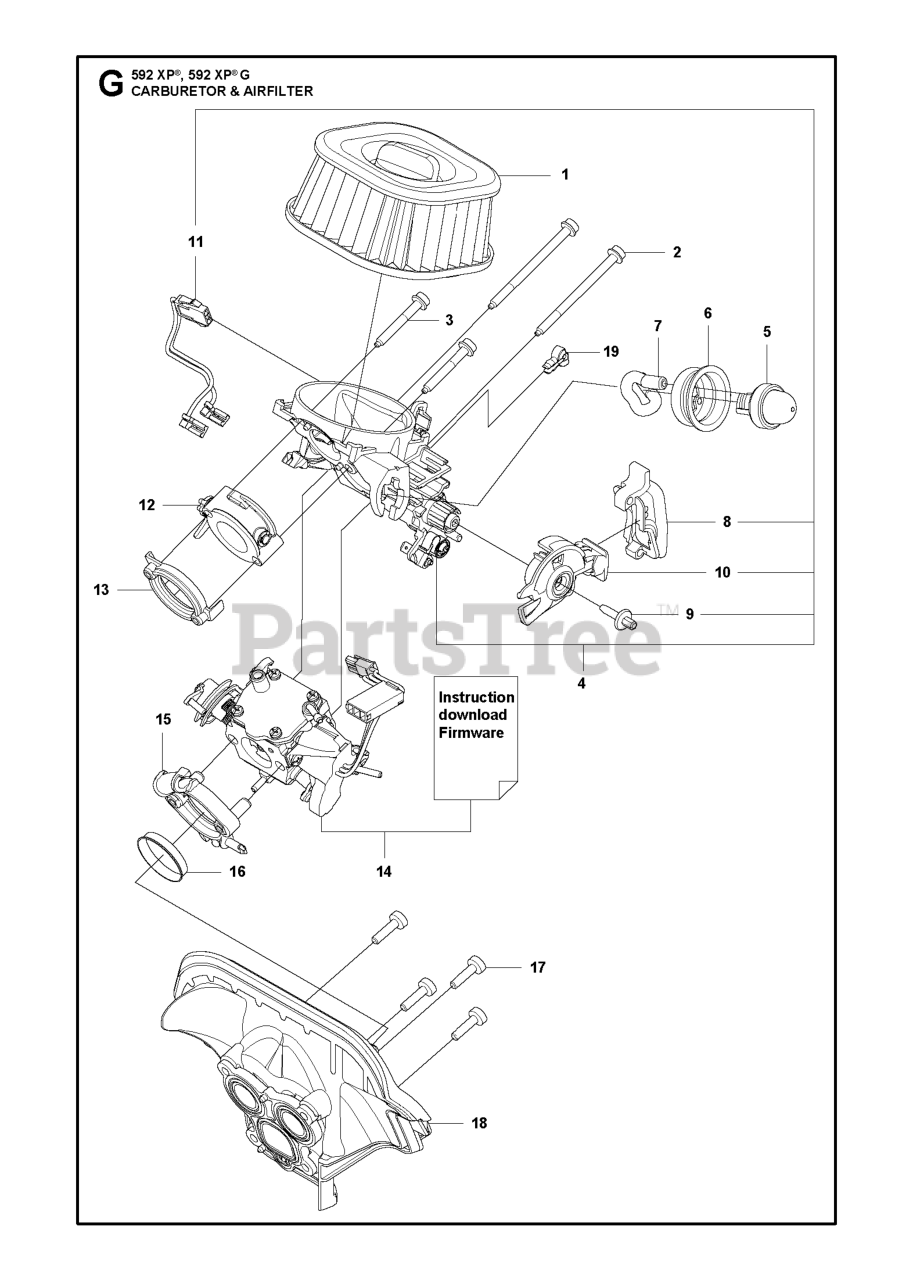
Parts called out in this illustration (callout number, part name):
1	AIR FILTER ASSY MESH NW
1	AIR FILTER ASSY MESH 50 MICRO
1	AIR FILTER ASSY MESH 27 MICRO
2	SCREW INTERNAL TORX HEAD FLANG
3	SCREW INTERNAL TORX HEAD FLANG
4	INLET ELBOW ASSY
5	AIR CLEANER ZAMA
6	SEALING PURGE
8	SEALING CHOKE CONTROL
10	CHOKE CONTROL ASSY
11	WIRING ASSY STOP
12	VALVE HOUSING ASSY
13	FLANGE VALVE HOUSING
14	CARBURETTOR KIT H592
15	FLANGE CARBURETTOR ASSY
16	SLEEVE INLET PIPE
17	SCREW ITXSCM M4X15 T27 12.9 T
18	INLET PIPE ASSY
